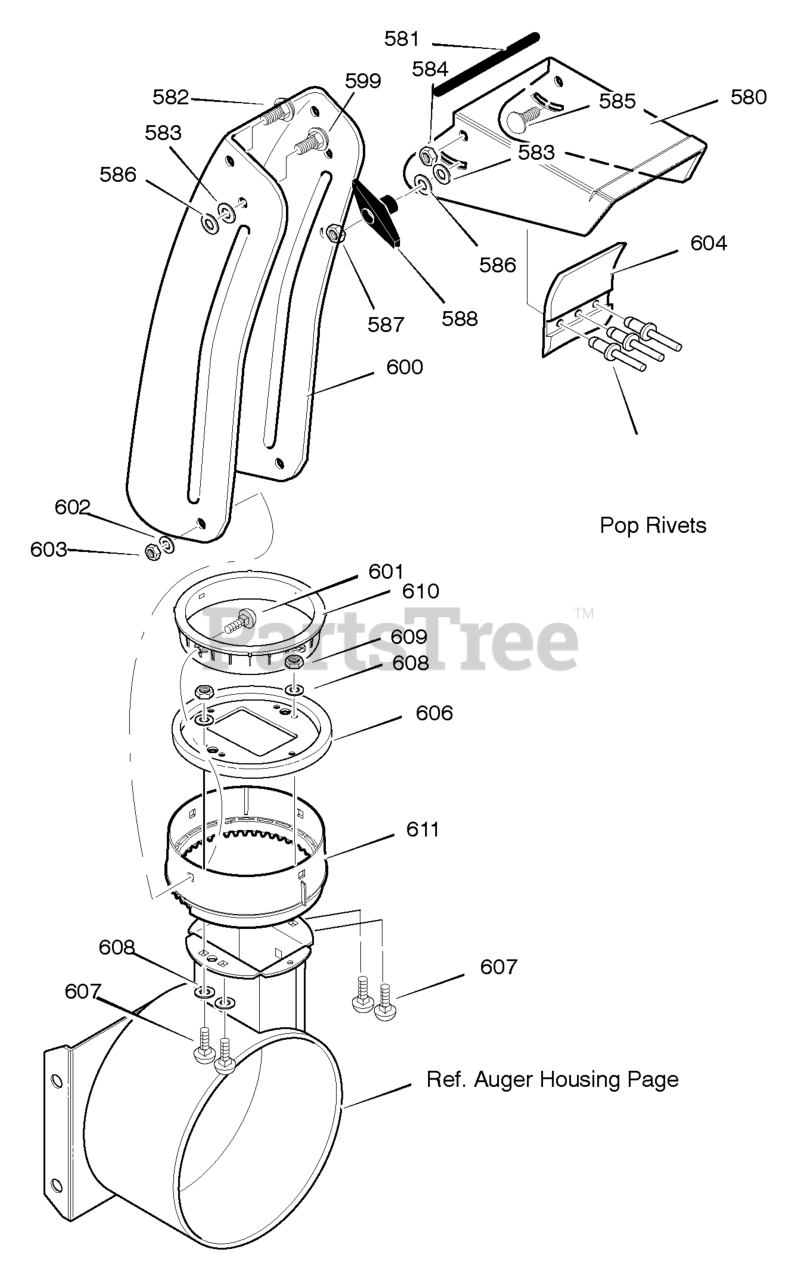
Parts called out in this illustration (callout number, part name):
580	CHUTE, UPPER
581	TRIM STRIP, BLACK
582	SCREW, 5/16-18 x 0.75
583	PLASTIC WASHER
584	NUT, 5/16-18 HEX NYLOCK
585	SCREW, 5/16-18 x 0.75
586	PLASTIC WASHER
587	NUT, 5/16-18 HEX
588	KNOB, T
599	BOLT, CARRIAGE 5/16-18 x 1.50
600	CHUTE, LOWER
601	BOLT, 5/16-18 x 1.00 CARRIAGE
602	WASHER, FLAT
603	NUT, 5/16-18 HEX NYLOCK
606	CHUTE COLLAR
607	BOLT, 1/4-20 x .75
608	WASHER, FLAT
609	NUT, 1/4-20 HEX NYLOCK
610	RETAINER, RING INNER
611	RING, OUTER CHUTE
